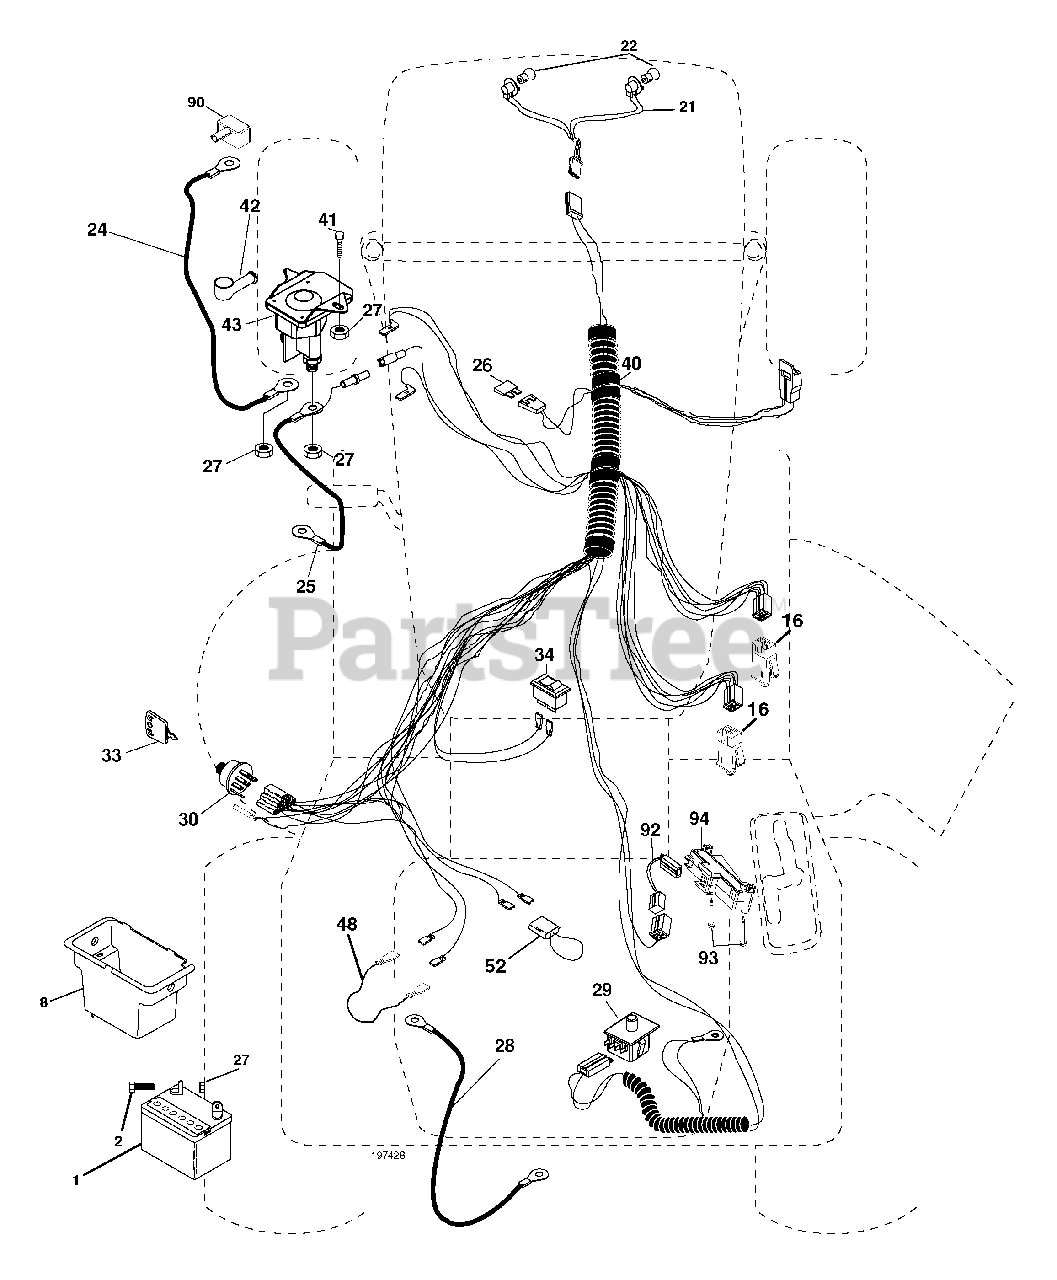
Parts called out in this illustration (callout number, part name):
1	Battery
2	Bolt Hex Hd 1/4-20 unc x 3/4
8	Box Battery
16	Switch Interlock
21	Harness Socket Light
22	Bulb, Light # 1156
24	Cable Battery
25	Cable Battery 6 Ga. Red w/16 wire 44"
26	Fuse
27	Nut Keps Hex 1/4-20 unc
28	Cable Ground 12" Blk 6 Ga.
29	Switch Seat
30	Switch Ign
33	Key Ign Molded Generic
34	Switch Light/Reset
40	Harness Ign
41	Bolt Fin Hex 1/4-20 unc x 1/2
42	Cover Terminal Red
43	Solenoid
48	Adapter Ammeter
52	Protection Loop
90	Cover Terminal
92	Harness Pigtail
93	Screw Plastite 10-1/4 x 2.0
94	Module Reverse ROS
